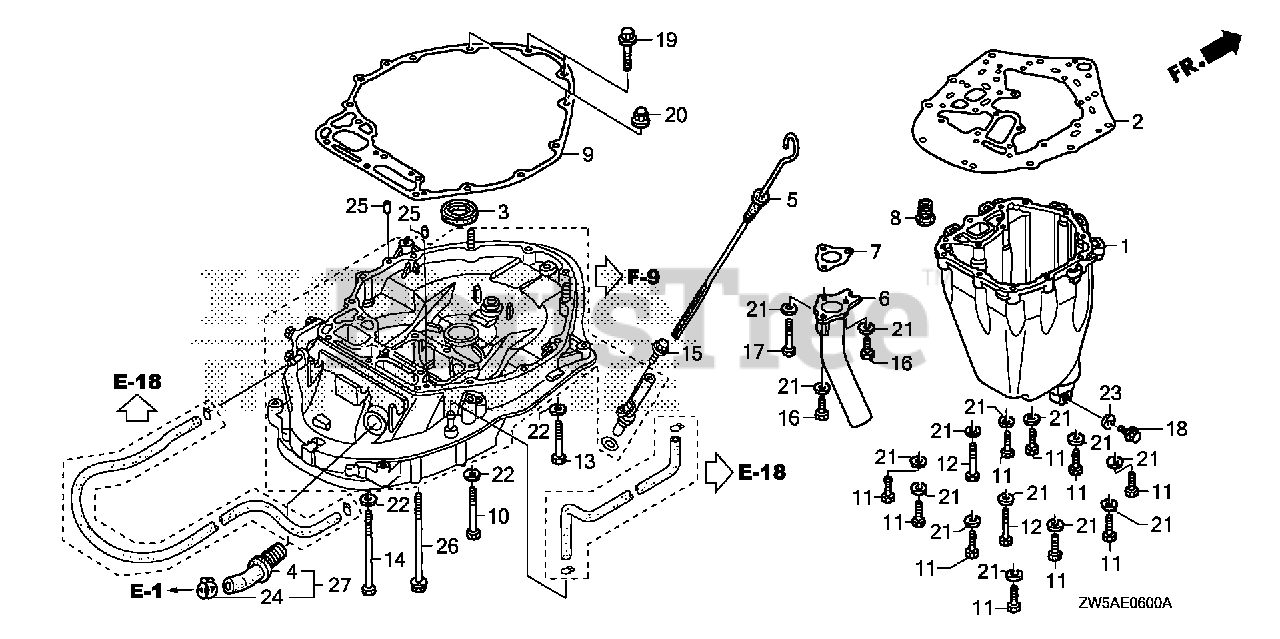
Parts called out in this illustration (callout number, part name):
1	PAN, OIL *TGRAY* (GRAY)
2	GASKET, OIL PAN
3	RUBBER, OIL PUMP
4	TUBE, OIL
5	GAUGE, OIL LEVEL
7	GASKET, EX. PIPE
8	GROMMET, WATER TUBE
9	GASKET, MOUNT CASE
10	BOLT, HEX. (10X60)
11	BOLT, HEX. (8X35)
12	BOLT, HEX. (8X55)
13	BOLT, HEX. (10X47)
14	BOLT, HEX. (10X110)
15	BOLT, FLANGE (6X12)
16	BOLT, HEX. (8X25)
17	BOLT, HEX. (8X65)
18	BOLT, DRAIN PLUG
19	BOLT, FLANGE (10X45)
20	NUT, CAP (10MM)
21	WASHER, PLAIN (8MM)
22	WASHER, PLAIN (10MM)
23	WASHER, DRAIN PLUG (12MM)
24	CLAMP, TUBE (D29)
25	PIN, DOWEL (6X10)
26	BOLT, FLANGE (10X130)
27	TUBE SET, OIL
